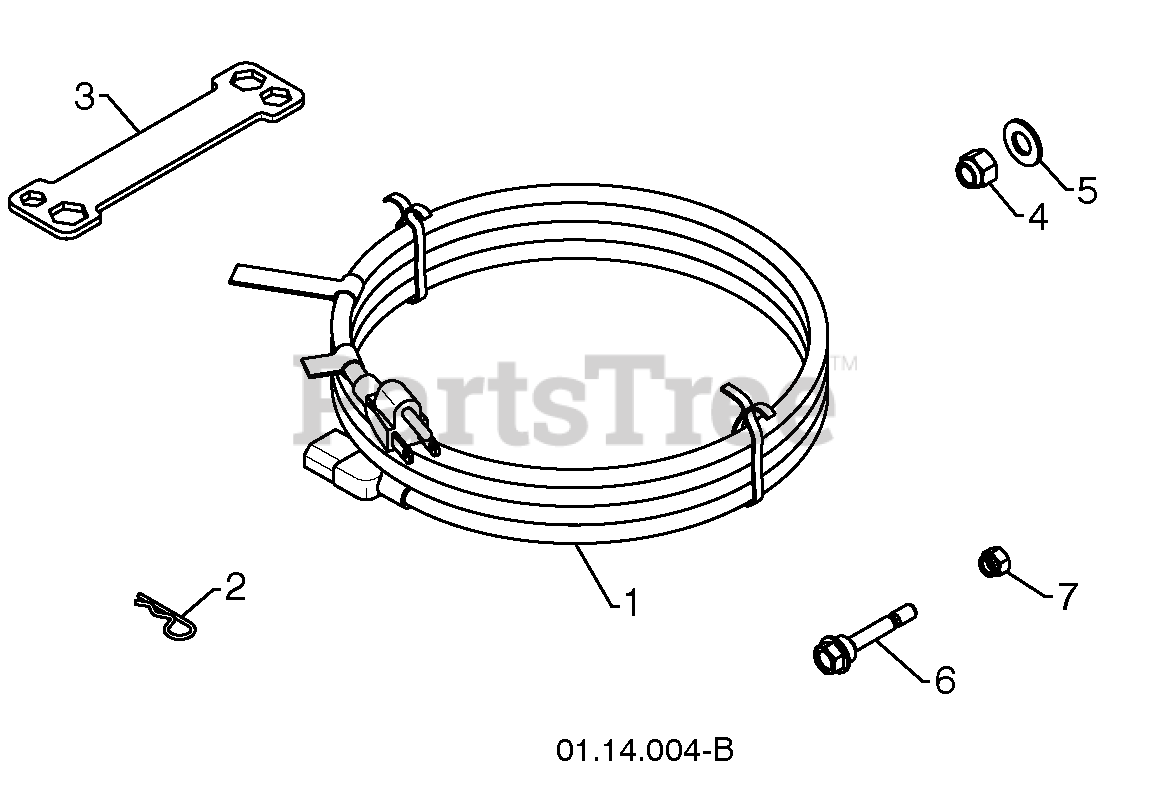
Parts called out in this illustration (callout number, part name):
1	POWER CORD
2	RETAINER PIN
3	WRENCH
4	LOCKNUT 3/8-16
5	WASHER 3/8
6	SHEAR BOLT 1/4-20 X 1-3/4
7	LOCKNUT 1/4-20
